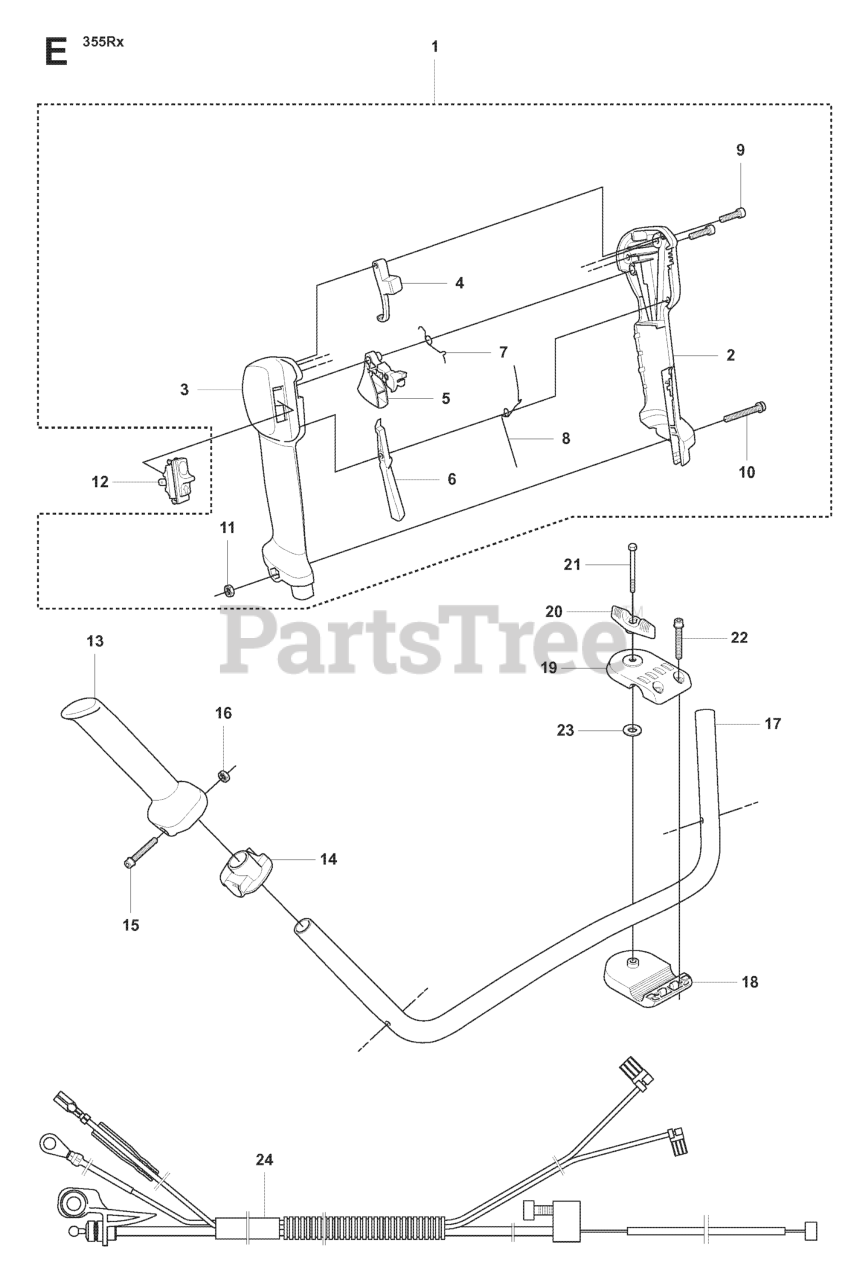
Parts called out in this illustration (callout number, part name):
1	THROTTLE HANDLE ASSY
2	HANDLE HALF RIGHT
3	HANDLE HALF LEFT
4	LOCKOUT STARTER THROTTLE
5	THROTTLE TRIGGER
6	THROTTLE LOCK
10	SCREW
12	STOP BUTTON
16	NUT M6M M5
17	HANDLE
18	HANDLE HOLDER LOWER
19	HANDLE HOLDER UPPER
21	%SCREW
